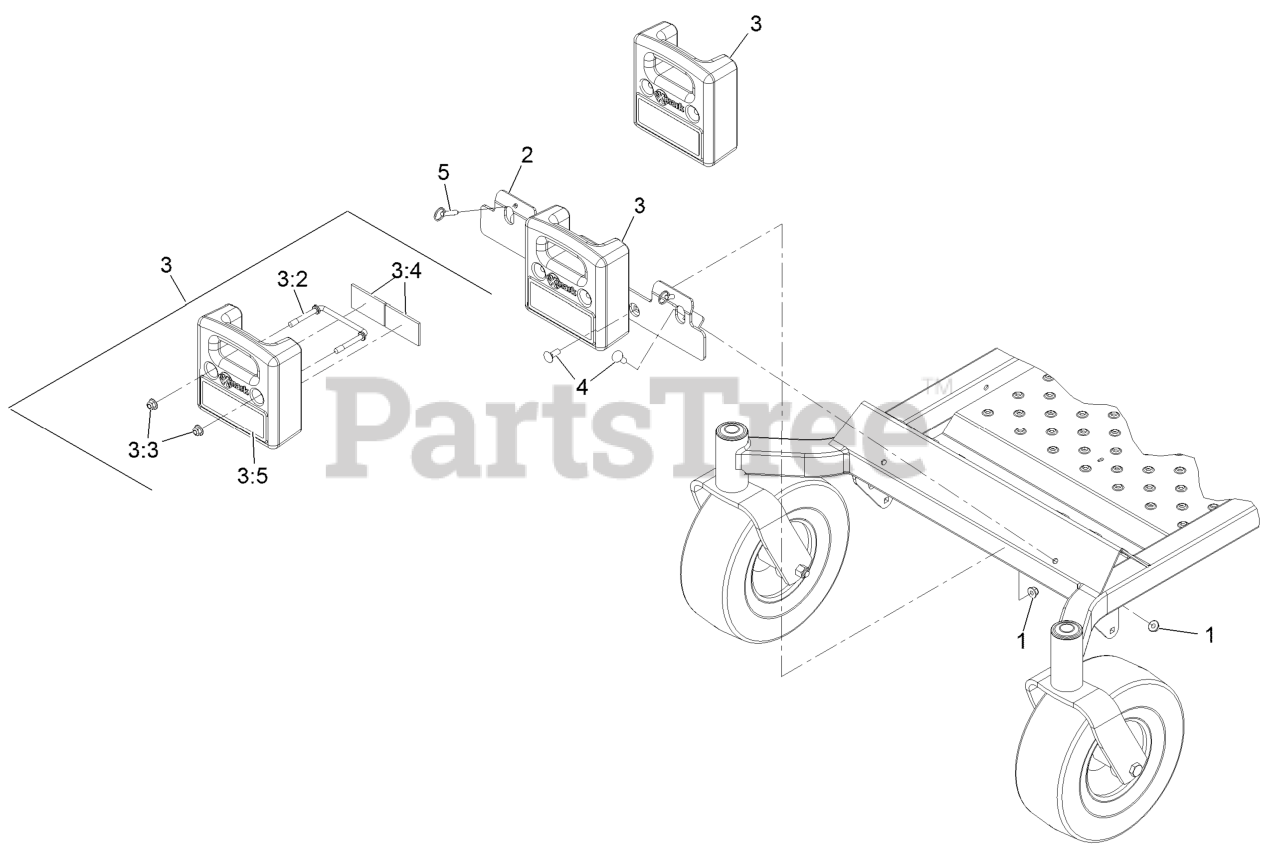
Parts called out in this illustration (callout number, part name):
1	NUT-HF, NI
2	THREE WEIGHT ASM
3	WEIGHT ASM
3:2	WIREFORM-WEIGHT
3:3	NUT-HF, NI
3:4	CUSHION-RUBBER
3:5	DECAL-WARNING WEIGHT
4	BOLT-CARR
5	PIN-BALL, DETENT
